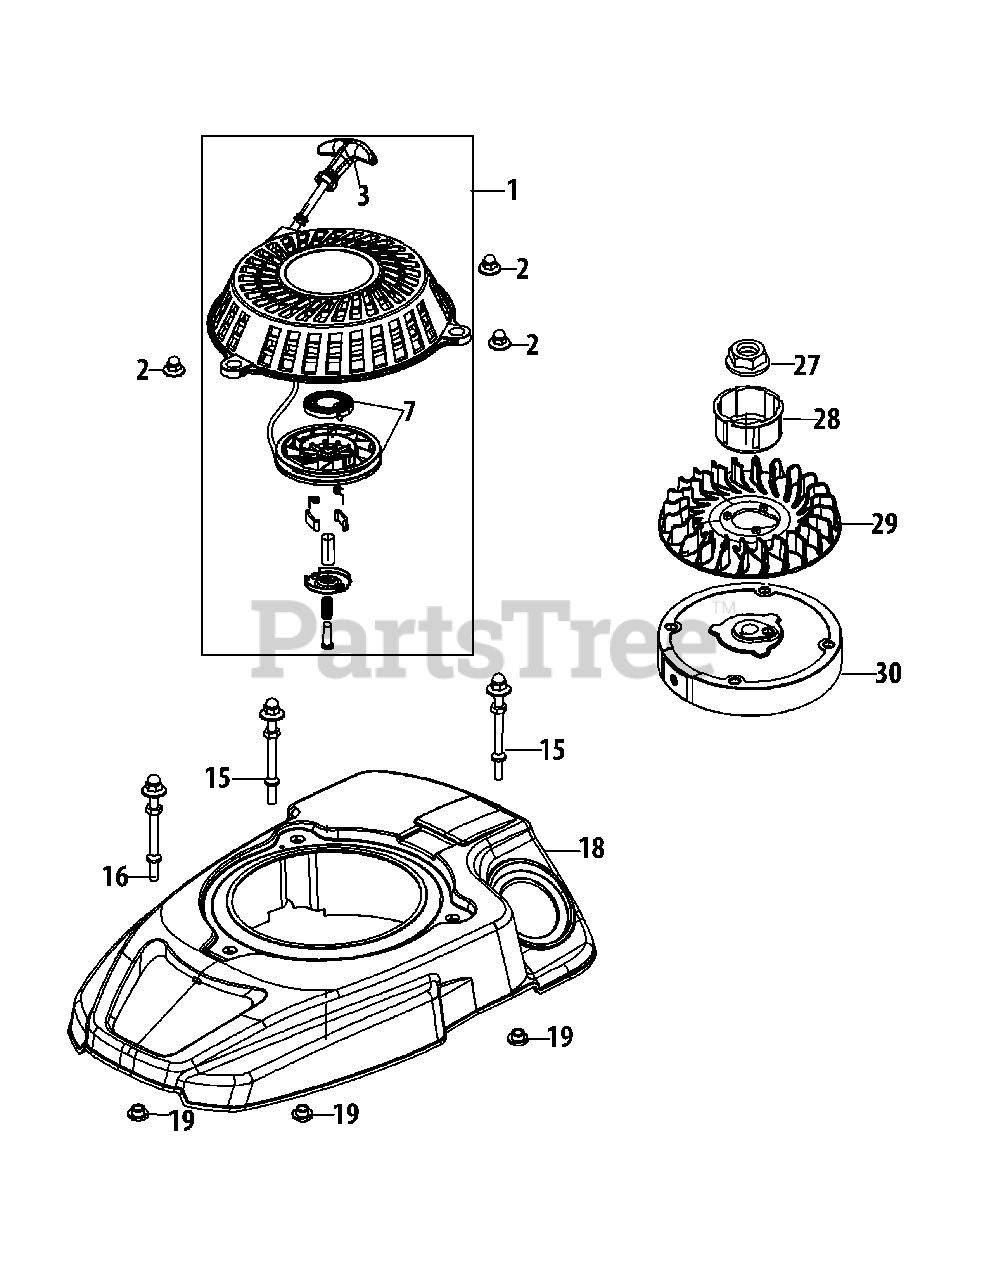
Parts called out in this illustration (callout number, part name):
1	Recoil Starter Assembly
2	Starter Acorn Nut
3	Starter Handle
7	Recoil Pulley & Spring Ass'Y
15	Starter/Shroud Rear Stud M6×78.5
16	Starter/Shroud Front Stud M6×74
18	Engine Shroud
19	Engine Shroud Spacer
27	Flywheel Nut M14
28	Starter Cup
29	Cooling Fan
30	Flywheel
